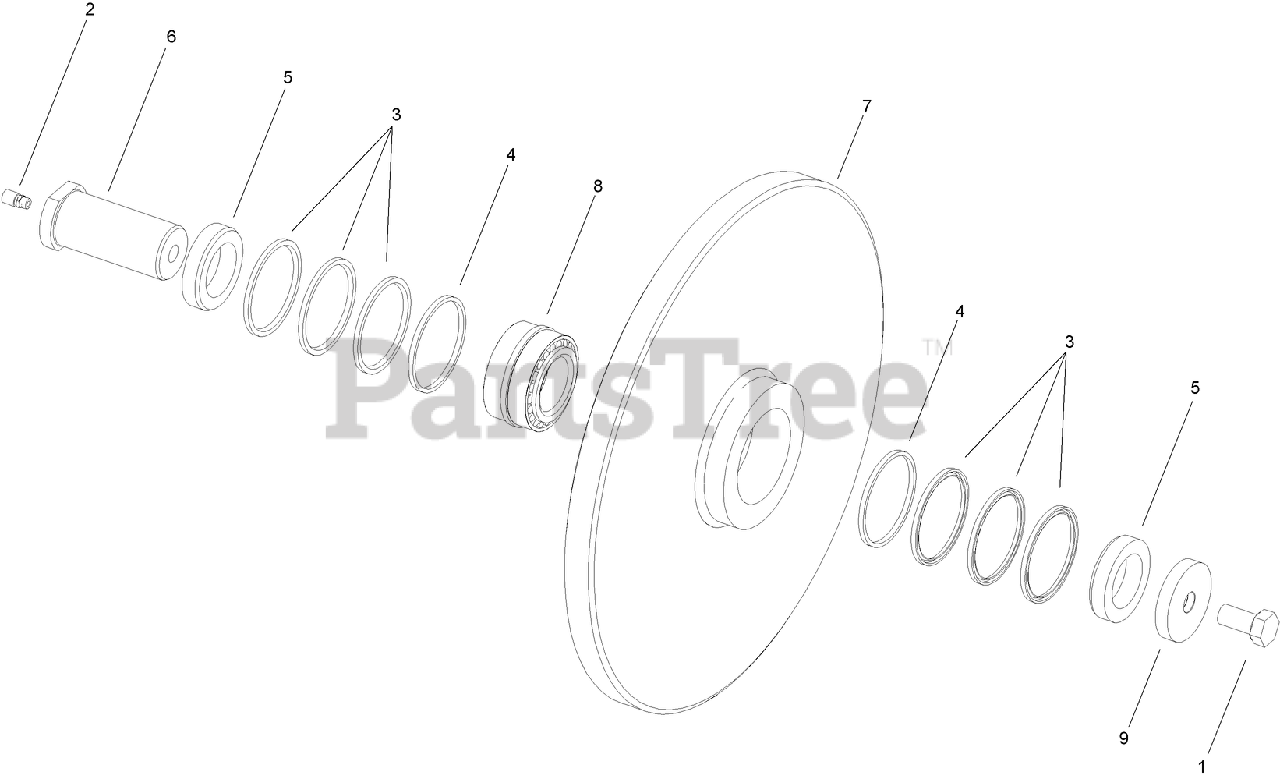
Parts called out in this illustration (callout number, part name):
2	FITTING-LUBE, STRAIGHT
3	SEAL-ROLLER
4	SPACER-SEAL, BOOM END
5	SPACER-BEARING
8	BEARING KIT
